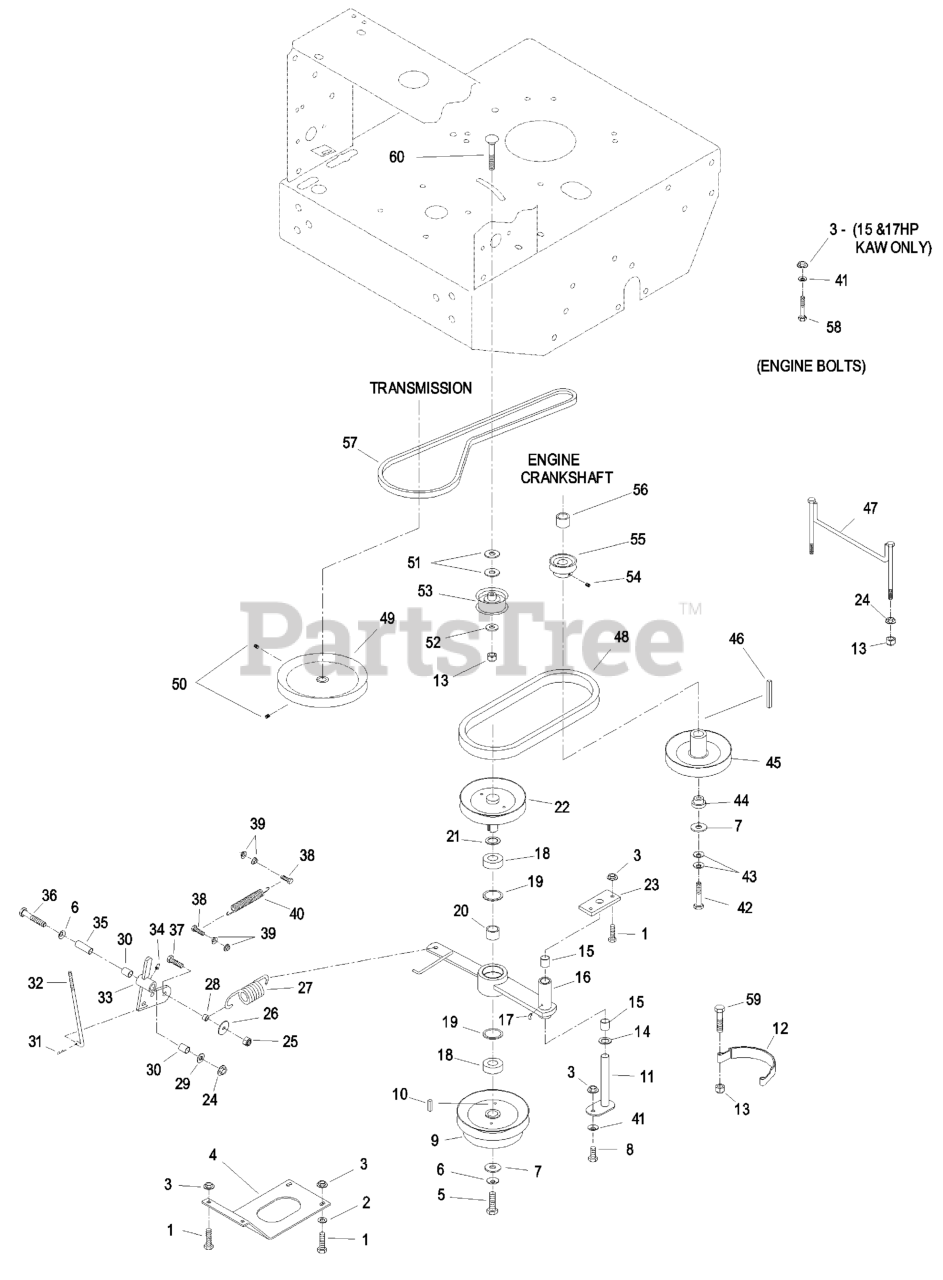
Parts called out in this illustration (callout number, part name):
4	PLATE-GUARD
5	SCRW,CAP HH
9	SHEAVE,6.13 W/HUB
11	WLD,PIN PIVOT
12	BAND,BRAKE BLADE
14	WASHER-SPACER
15	SLEEVE,BEARING
17	1481
18	BEARING,CLUTCH SHAFT
20	SPACER,CLUTCH BEARING
21	WASHER-SPACER
22	SHEAVE,6.13 W/SHAFT
23	PLATE-CLUTCH PIVOT
27	SPRING,BELT TENSION
28	SPACER,CLUTCH ANCHOR
30	SLEEVE-BEARING
31	PIN-COTTER
32	LINKAGE,LOWER
33	ASM,PIVOT W/BUSHINGS
35	BUSHING
40	SPRING,EXTENSION
41	WASHER-SPRING
43	WASHER-SPRING
44	BUSHING,CLUTCH KEEPER
45	SHEAVE,ENGINE
46	KEY,MACH 1/4X1/4X2-5/8
47	GUIDE - BELT
48	BELT,BLADE CLUTCH
49	SHEAVE-TRANSMISSION
54	SCREW-SET
55	SHEAVE-TRANSMISSION
56	SPACER,CRANKSHAFT
57	BELT,TRANS DRIVE
